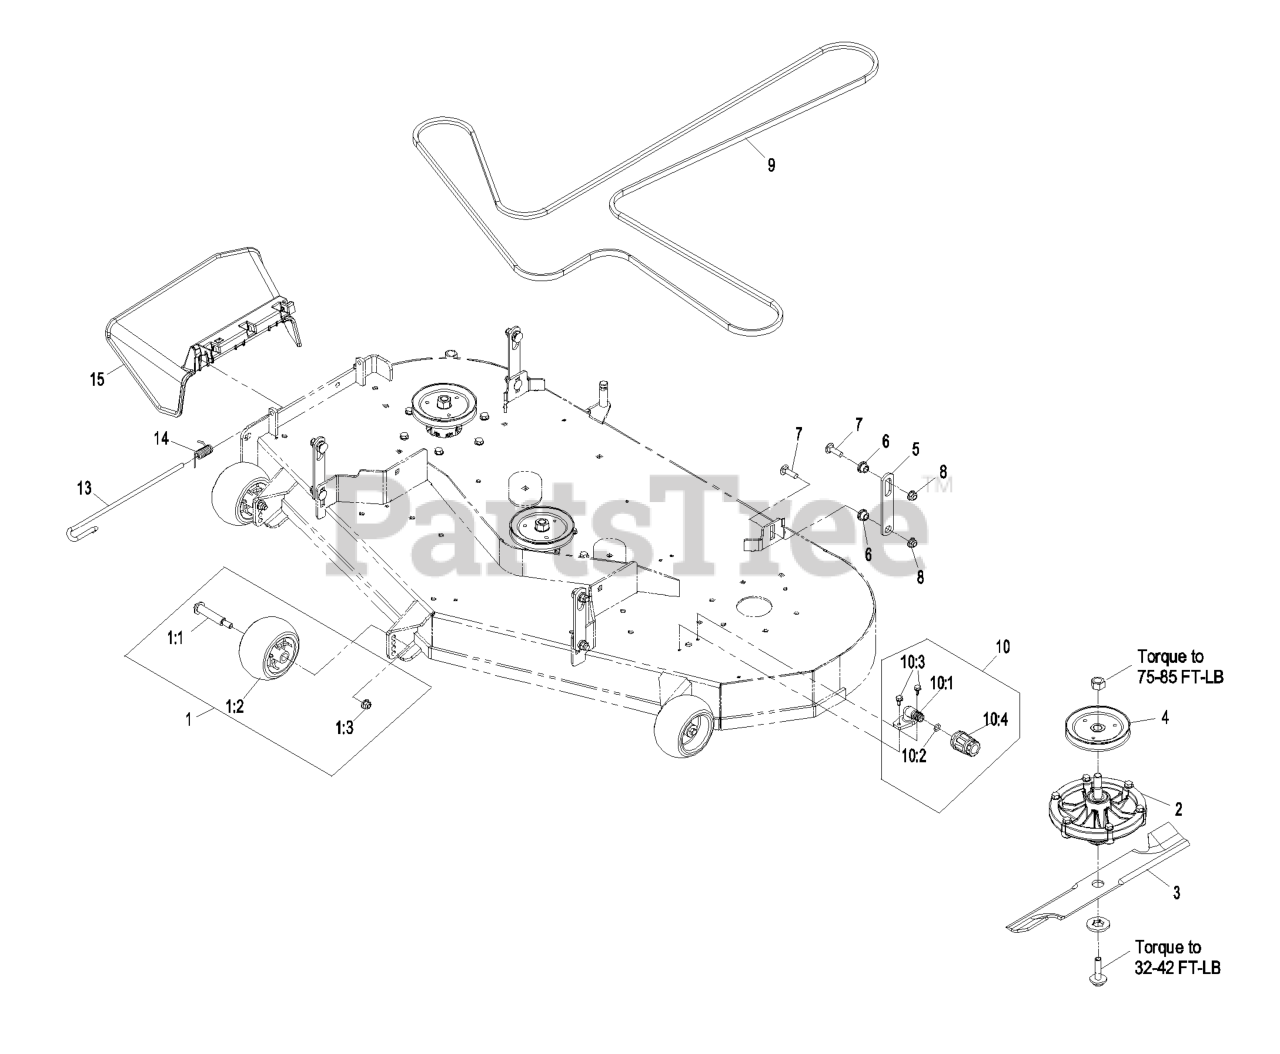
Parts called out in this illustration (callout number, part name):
1	ANTI-SCALP ROLLER KIT
1:1	BOLT-SHOULDER
1:2	ROLLER-SCALP, ANTI
1:3	NUT-HF, NI
5	HANGER-DECK
6	BUSHING-FLANGED
7	BOLT-CARR
8	NUT-HF, NI
9	BELT
10	WASHOUT PORT KIT
10:3	SCREW-HWH
10:4	CONNECTOR-HOSE
13	PIN-CHUTE
14	SPRING-TORSION
15	CHUTE DEFLECTOR XRK M056
